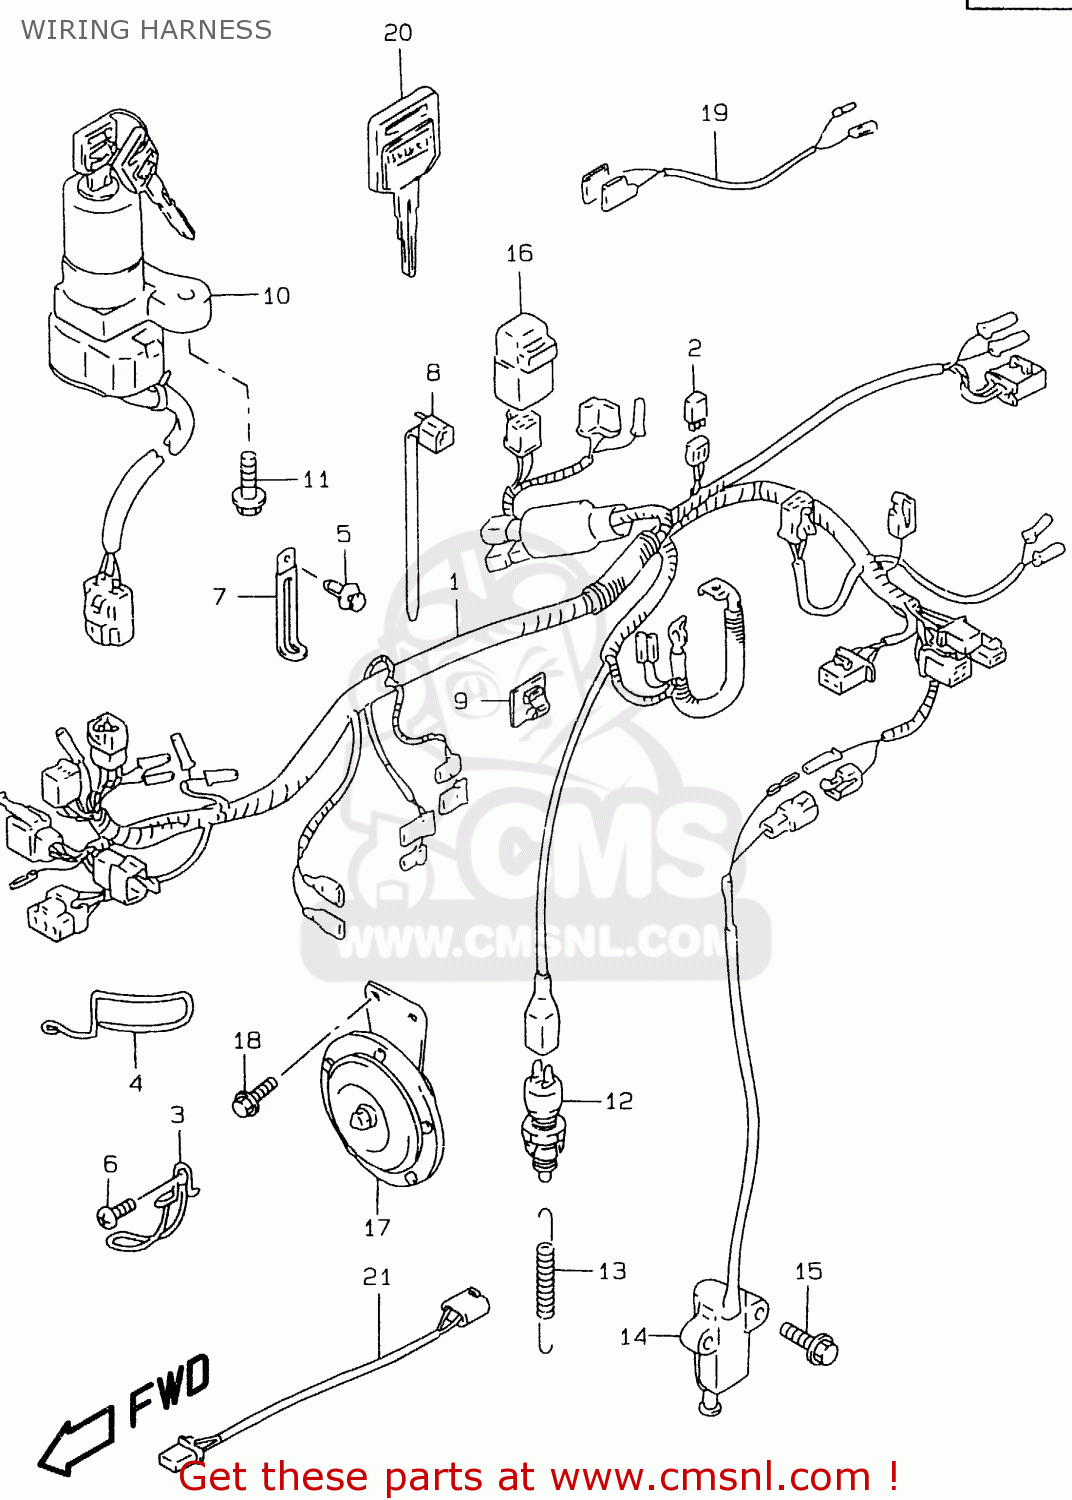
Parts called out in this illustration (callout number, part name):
1	HARNESS,WIRING
2	DIODE(STANLEY DE8804)
3	PROTECTOR
4	PROTECTOR
5	CLIP(BLACK)
6	SCREW 6X12
7	CLAMP(L:65)
8	CLAMP L:165
9	CLAMP
10	LOCK ASSY,STEERING
11	SCREW(6X18)
12	SWITCH ASSY,STOP LAMP
13	SPRING
14	SWITCH ASSY,SIDE STAND
15	BOLT
16	RELAY ASSY
17	HORN ASSY
18	BOLT
19	WIRE,CLUTCH LEAD
20	KEY,BLANK
21	WIRE,AIR SOLENOID
